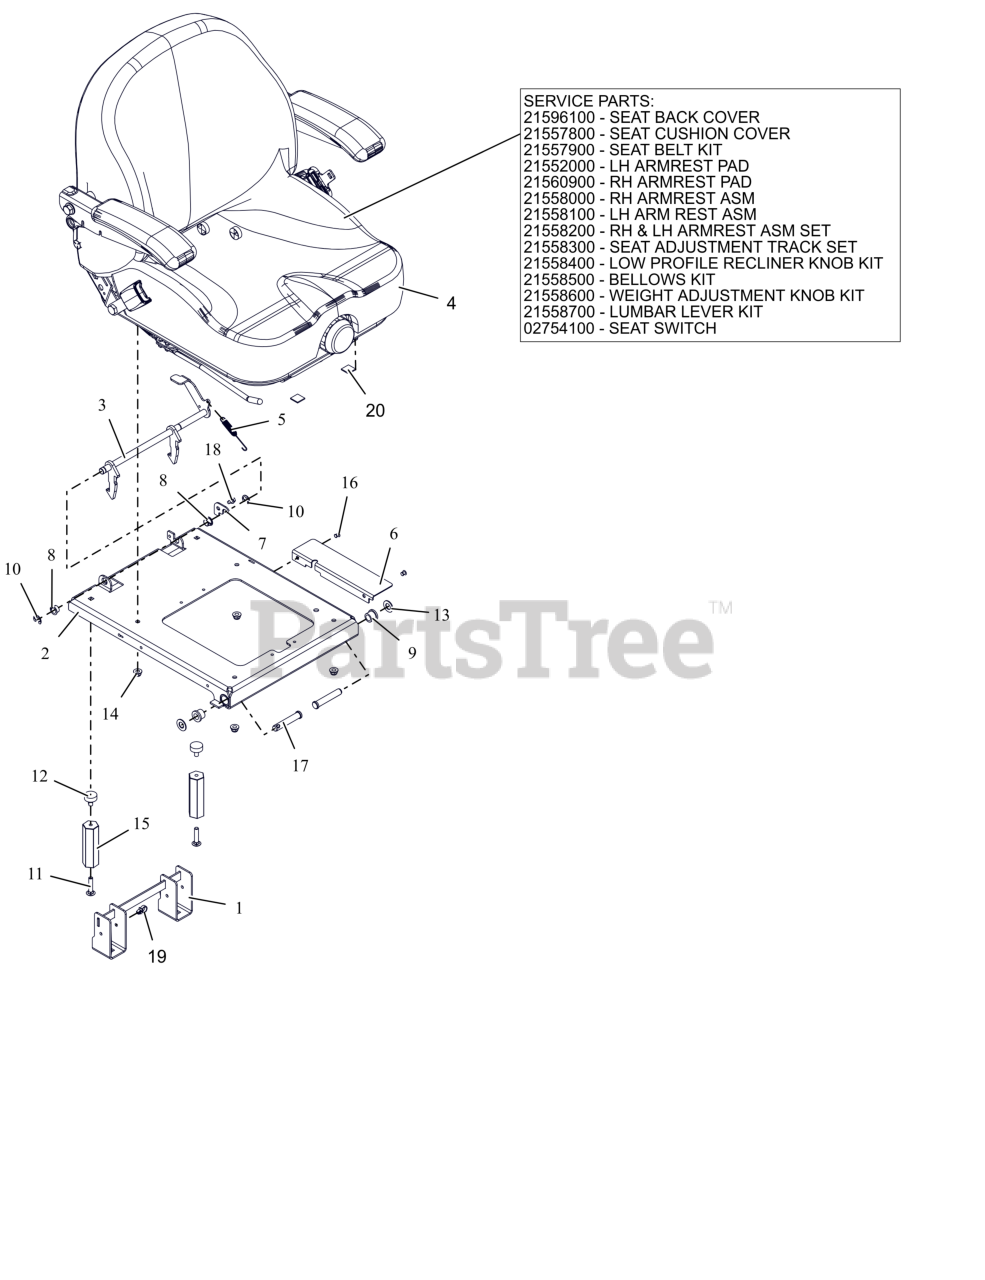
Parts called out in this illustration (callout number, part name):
1	WLDMT, LATCH RECEIVER
2	WLDMT- MECH. SUSP. SEAT PLATE
3	WLDMT- SUSP. SEAT LATCH
4	SEAT-MECH. SUSP. 18"
4	COVER SEAT BACK
4	SEAT CUSHION COVER
4	SEAT BELT KIT
4	PAD, ARMREST
4	PAD, ARMREST (HARD)
4	RH ARMREST ASM
4	LH ARMREST ASM
4	RH & LH ARMREST ASM SET
4	SEAT ADJUSTMENT
4	KIT, LOW PROFILE RECLINER KNOB
4	BELLOWS KIT
4	WEIGHT ADJUSTMENT KNOB KIT
4	LUMBAR LEVER KIT
4	SWITCH- SNAP MTG N.O.
5	SG-TENS .043X.44X3.31 WLD 5.8
6	GUARD- SEAT PLATE
7	BRKT- ROD KEEPER
8	BUSHING, POLYLINER-.50 SPLIT
9	BSHG, FLG .516X.750X.625X.937
10	RG-RTNG-EXT .500X.042 (E)
11	BLT,RHSN .31-18X1.50 G5 ZCC
12	BUMPER, RUBBER
13	WSHR, FLT .531X1.00X.063 ZCC
14	NUT,LK-NYL-FLG .31-18 G5ZC120
15	NUT- COUPLER 5/16-18X1.12X3.8
16	RIVET, .1875 AL/AL .126-.250
17	PIN-CLIC .50X2.70X2.31 -ZCC
18	SCR,TAP .25-20X.375 HWH TR ZCC
19	ROUTING CLIP (1/2" ID)
